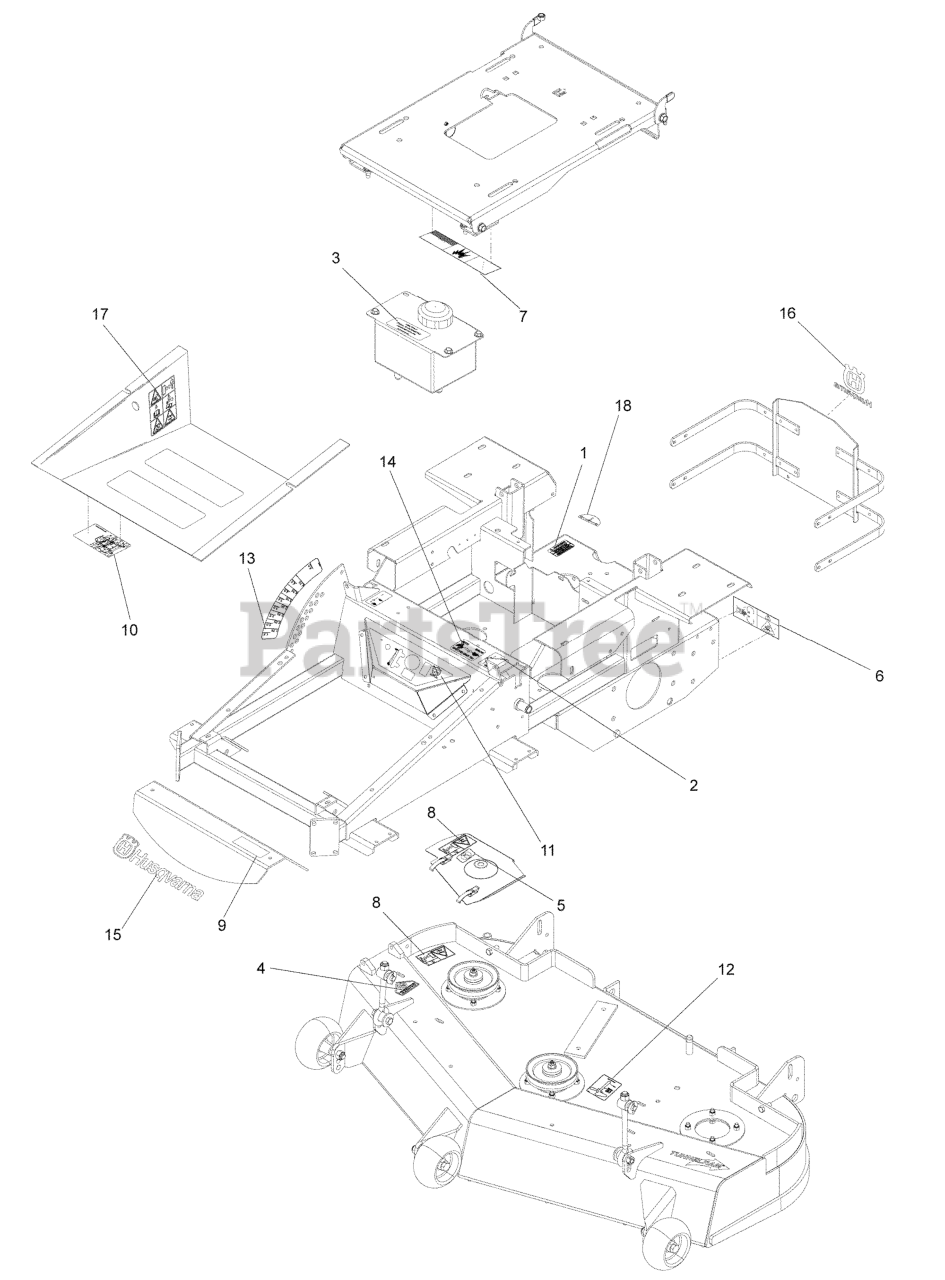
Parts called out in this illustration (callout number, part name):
1	DECAL, PROP. 65
2	DECAL, MOTION CONTROL
3	DECAL, OIL TANK
4	DECAL, CPSC
5	DECAL, NO STEP
6	DECAL, BELT DRIVE
7	EURO DECAL-BATTERY WARNIN6
8	DECAL, EURO SEVERING
9	DECAL, IZ4217
10	SERVICE DECAL
11	DECAL, CONSOLE
12	DECAL, BELT ROUTING
13	DECAL, HEIGHT ADJ
14	DECAL, F.S.T.
15	DECAL, HUSQ 12" BLUE
16	DECAL, CROWN H 5-1/4 SILVER
17	DECAL, WARNING
18	DECAL, FUEL VALVE
